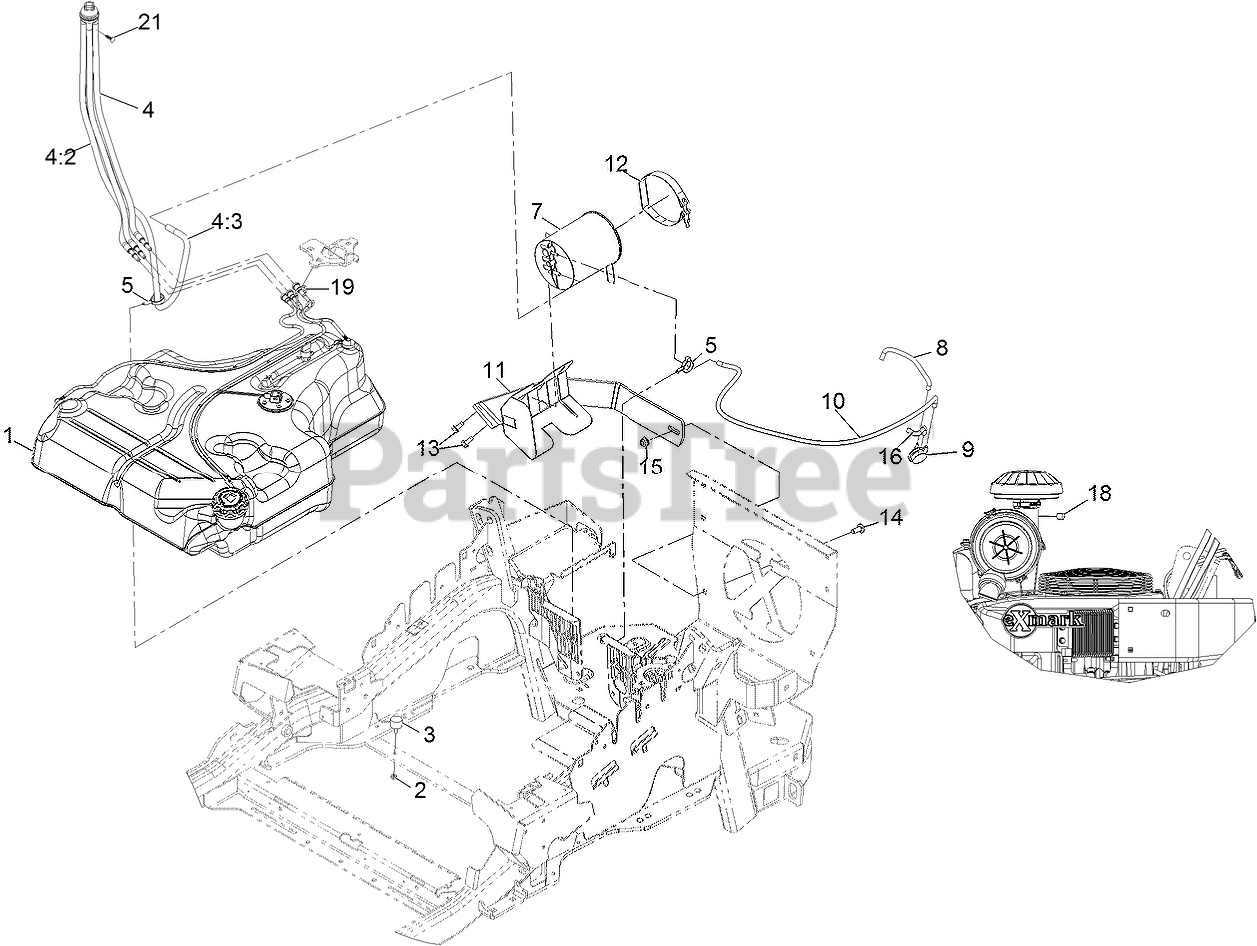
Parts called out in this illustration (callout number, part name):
1	ASM-8 GALLON FUEL TANK
2	NUT-JAM
4	FUEL MANIFOLD VENT ASM
4:2	HOSE-FUEL
4:3	HOSE-FUEL
5	CLAMP-HOSE
7	CANISTER-CARBON, 1200CC
8	HOSE-VENT,FORMED
9	VALVE-CONTROL, VACUUM
10	HOSE,VENT,FORMED
11	MOUNT-CANISTER
12	CLAMP, T-BOLT
13	Screw-HWH 5/16-18 X 3/4 Tf
14	SCREW-CARR
15	NUT-HF, NI
16	HOSE-VENT, FORMED
18	PLUG-PORT
19	RETAINER-LINE, VAPOR
21	PLUG-PLASTIC
